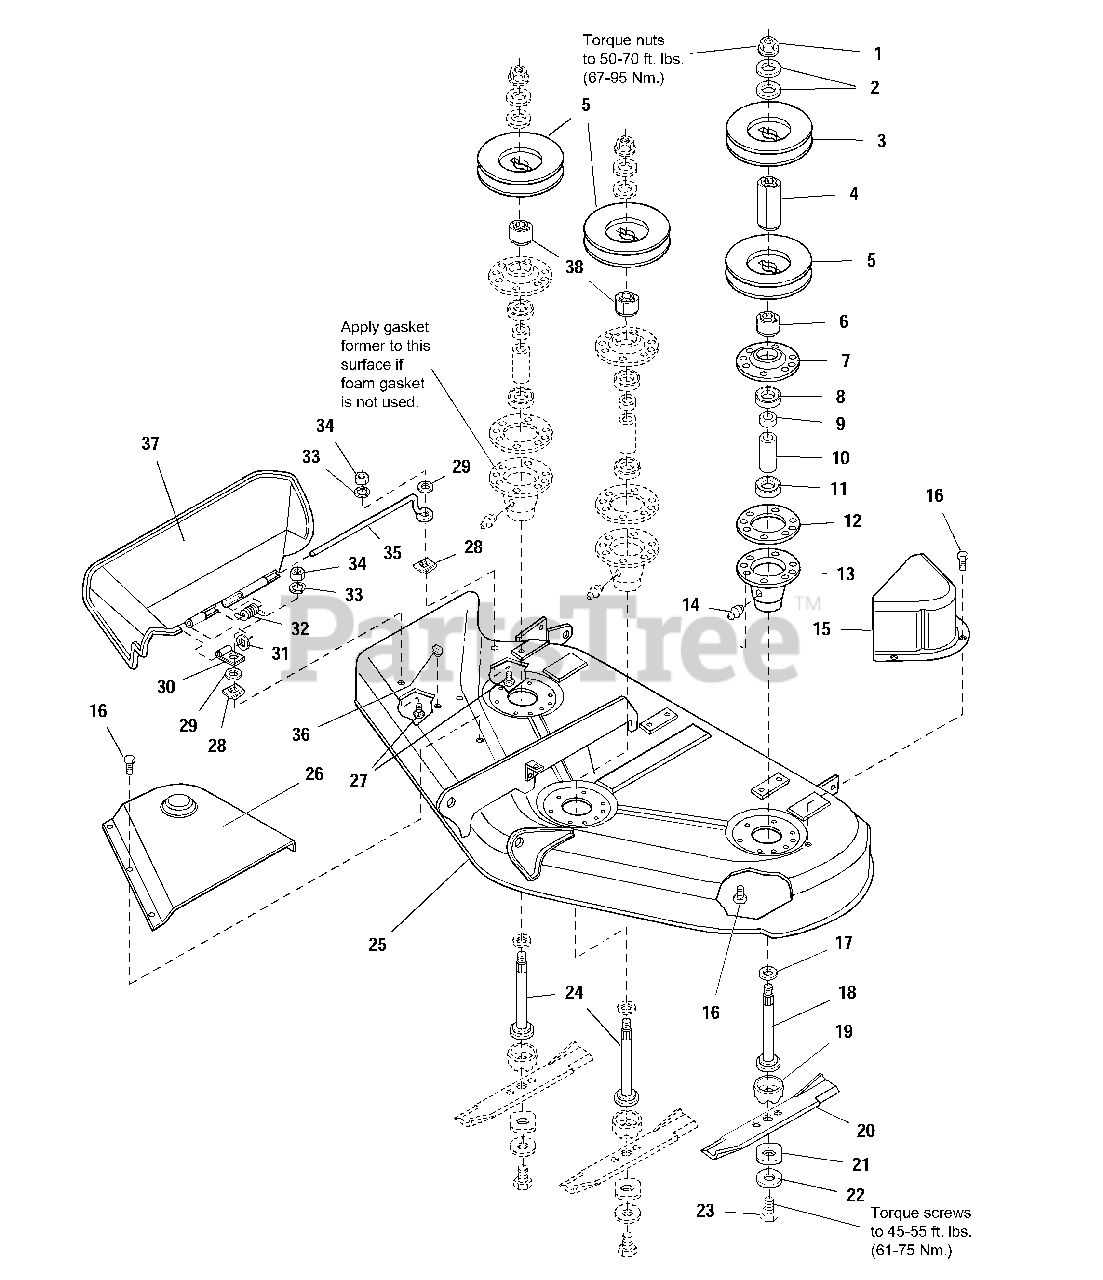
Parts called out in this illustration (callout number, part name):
1	NUT, Hex Flange, 9/16-8
2	WASHER, Belleville
4	HUB, Double Pulley, LH Arbor
6	HUB, Double Pulley, LH Arbor
7	COVER, Arbor Housing
9	SPACER, Bearing Sleeve
12	GASKET, Foam
13	HOUSING ASSEMBLY, Arbor Bottom, w/Lube Fitting
14	FITTING, Grease
15	COVER, Arbor
16	CAPSCREW, Taptite, 5/16-18 x 3/4
18	SHAFT, Arbor (LH)
19	SHIELD, Grass, Lower
20	BLADE, Mower, 16-1/8
21	WASHER, Hex
22	WASHER, Spring
23	CAPSCREW, Hex Hd, 7/16-14 x 1-1/4
24	SHAFT, Arbor (Center & RH)
25	MOWER HOUSING ASSEMBLY, 44" Mower (Orange)
25	MOWER HOUSING ASSEMBLY, 44" Mower (Black)
26	COVER, Arbor
27	CARRIAGE BOLT, 1/4-20 x 7/8
28	NUT, Push
29	WASHER, Plain
31	WASHER, 5/16
33	LOCKWASHER, 1/4
34	NUT, Hex, 1/4-20 UNC
35	ROD, Deflector, Front
37	DEFLECTOR, Plastic
38	HUB, Pulley, RH & Center Arbor
